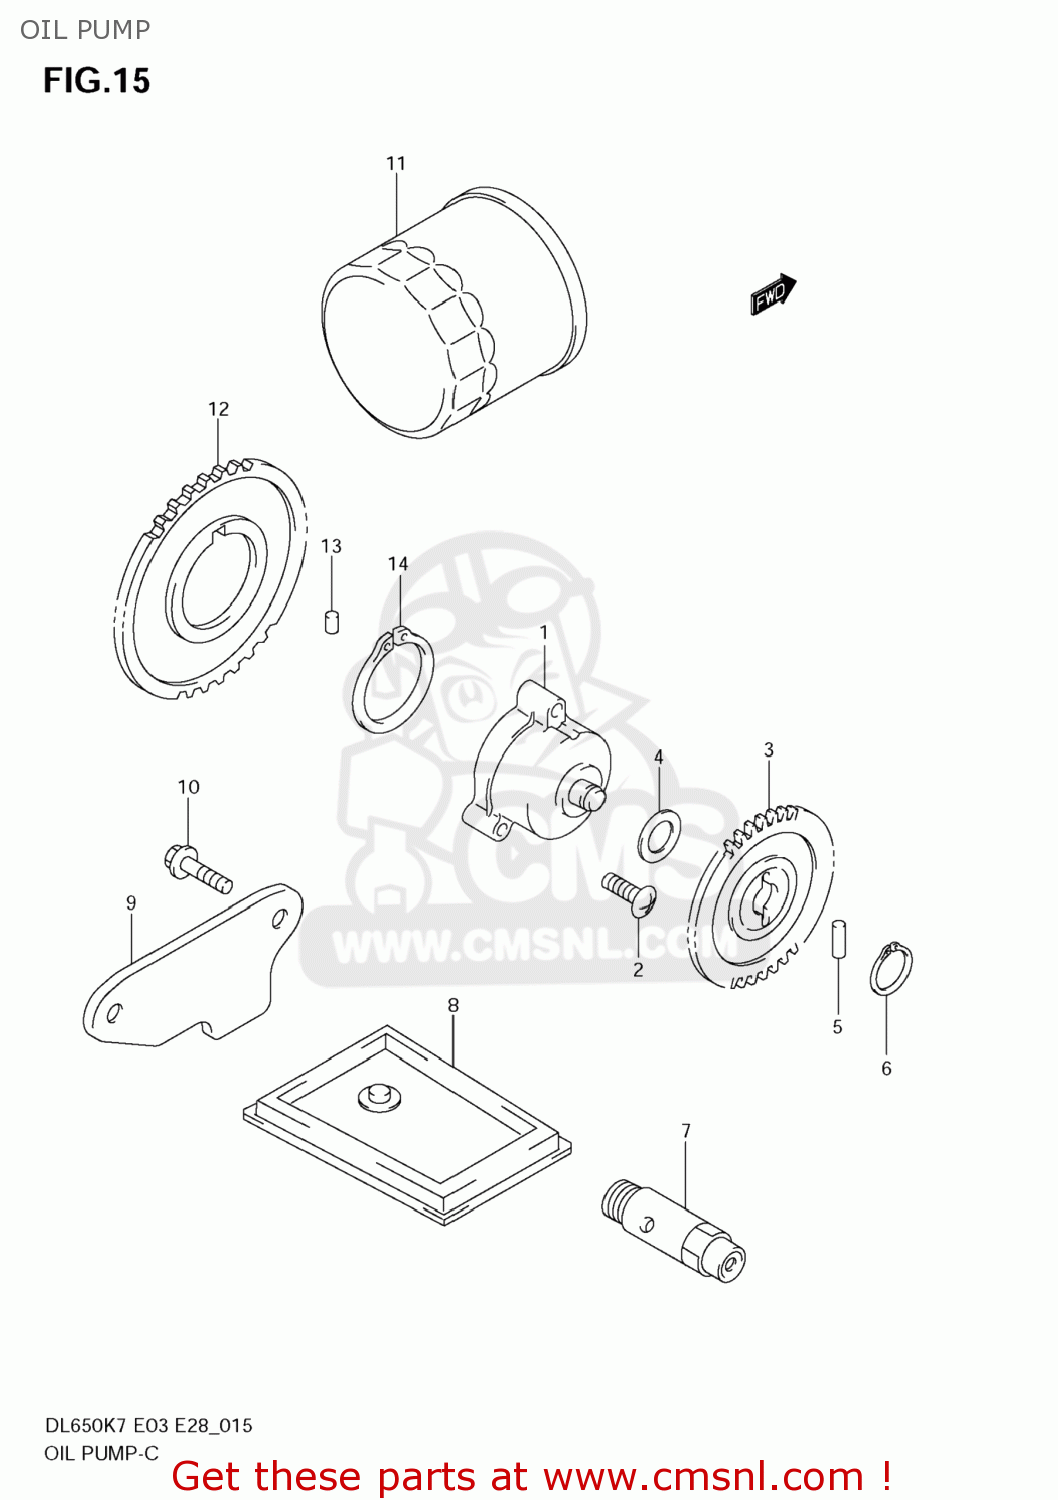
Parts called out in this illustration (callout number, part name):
1	PUMP ASSY,ENGINE OIL
2	BOLT
3	GEAR,ENG OIL PUMP DRIVEN
4	SHIM(10X18X0.5)
5	PIN(4X18.5)
6	CIRCLIP,10MM
7	VALVE ASSY,OIL RELIEF
8	STRAINER,ENGINE OIL
9	CAP,OIL STRAINER
10	BOLT
11	FILTER ASSY,EN
12	GEAR,ENG OIL PUMP DRIVE
13	PIN(6X6)
14	CIRCLIP
